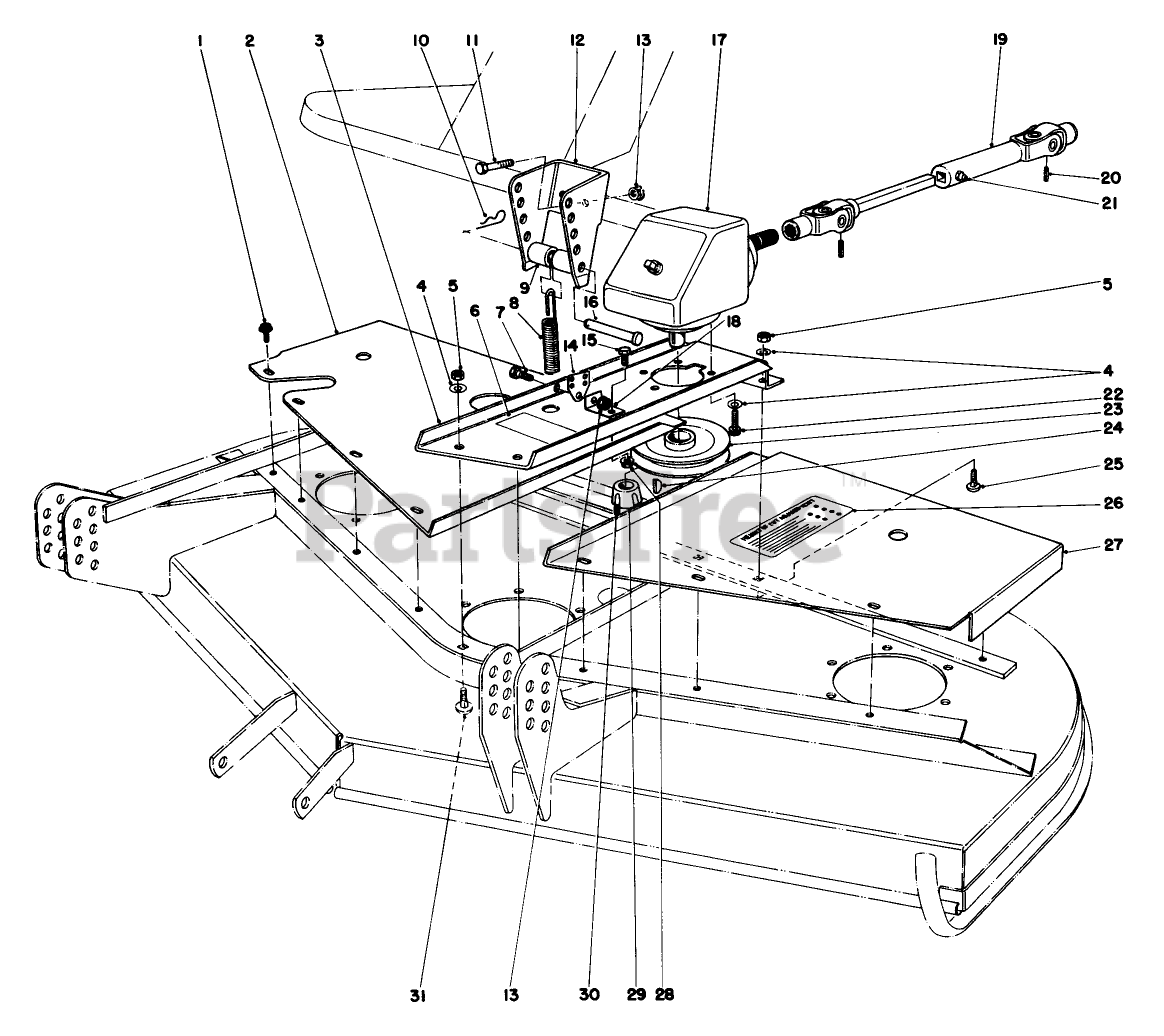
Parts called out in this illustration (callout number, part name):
1	SCREW-HHFTF
2	RH COVER WA *R
4	WASHER-LOCK
5	NUT-HEX
7	BOLT-SHOULDER
9	SPACER
10	PIN-HAIR
11	SCREW-HH
12	SPRING BRACKET *R
13	NUT-HHF, WHIZ
15	SCREW-HH
16	PIN-CLEVIS
18	EXTENSION BRKT *R
19	UNIVERSAL JOINT
20	PIN-ROLL
21	FITTING-GREASE
22	SCREW-HSH
24	KEY-WOODRUFF
25	SCREW-HH
27	LH COVER WA *R
28	NUT-HF
29	BUSHING-LOCK, TAPER
30	SCREW-SET, HSH
31	SCREW-CARR
